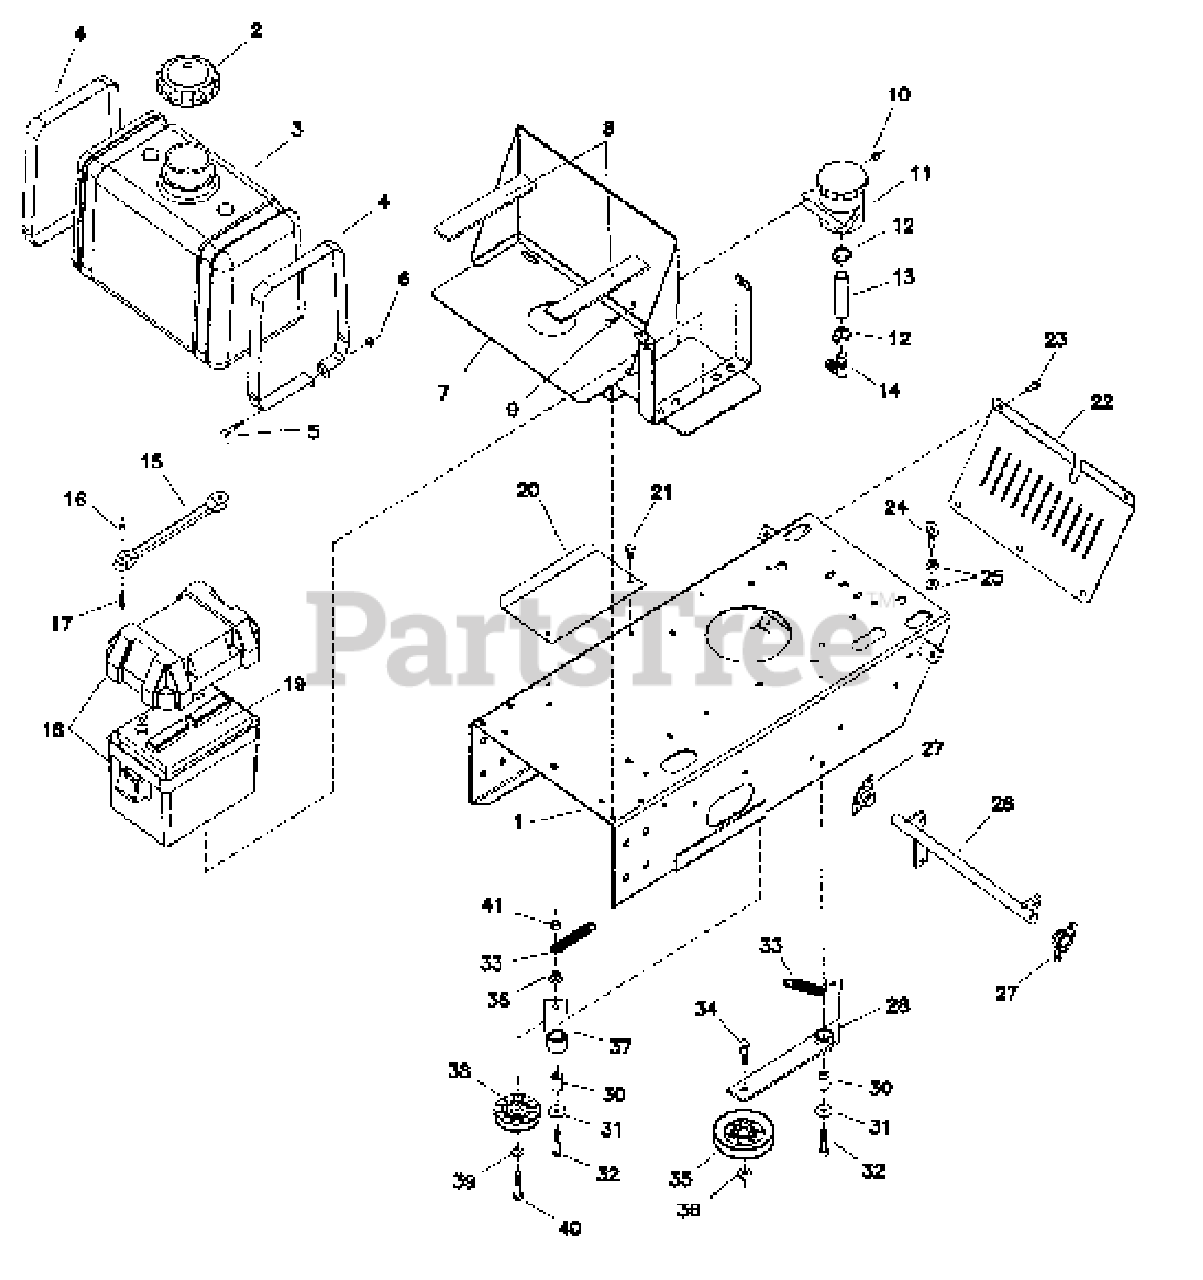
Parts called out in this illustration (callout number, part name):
1	PACER ENGINE DECK
2	CAP, Fuel Tank
3	FUEL TANK, 5 Gallon
4	STRAP, Fuel Tank
5	CAPSCREW, Hex Head, 1/4-20 x 1-1/2
6	NUT, Hex, Serrated Flange, 1/4-20
7	FUELT TANK MOUNT
8	RUBBER PAD
9	CARRIAGE BOLT, 1/4-20 x 3/4
10	NUT, Hex, Nylon Lock, 1/4-20
11	RESERVOIR, Hydraulic Oil
12	HOSE CLAMP
14	FITTING, 90 Deg.
15	RUBBER STRAP
16	NUT, Hex, Nylon Lock, #10-24
17	SCREW, Phillips, #10-24 x 1
18	BATTERY BOX
19	BATTERY
20	HEAT SHIELD
21	CAPSCREW, Hex Head, 5/16-18 x 3/4
22	SCREEN
23	CAPSCREW, Hex Head, Taptite, 1/4-20 x 3/4
25	NUT, Hex, Serrated Flange, 5/16-18
26	TRANSMISSION CONTROL SHAFT
27	BEARING, Flange
28	IDLER ARM, Complete (Includes Ref 29)
29	BUSHING
30	SPACER, Pivot
31	WASHER, Fender, 5/16
32	CAPSCREW, Hex Head, 5/16-18 x 1-3/4
33	SPRING, Extension
34	CAPSREW, Hex Head, 3/8-16 x 1-1/2
35	PULLEY, Idler
36	NUT, Hex Serrated Flange, 3/8-16
37	IDLER ARM, Complete (Includes Ref 29)
38	PULLEY, Idler
39	WASHER, 3/8
40	CAPSCREW, Hex Head, 3/8-16 x 2
41	NUT, Hex, Nylon Lock, 3/8-16
